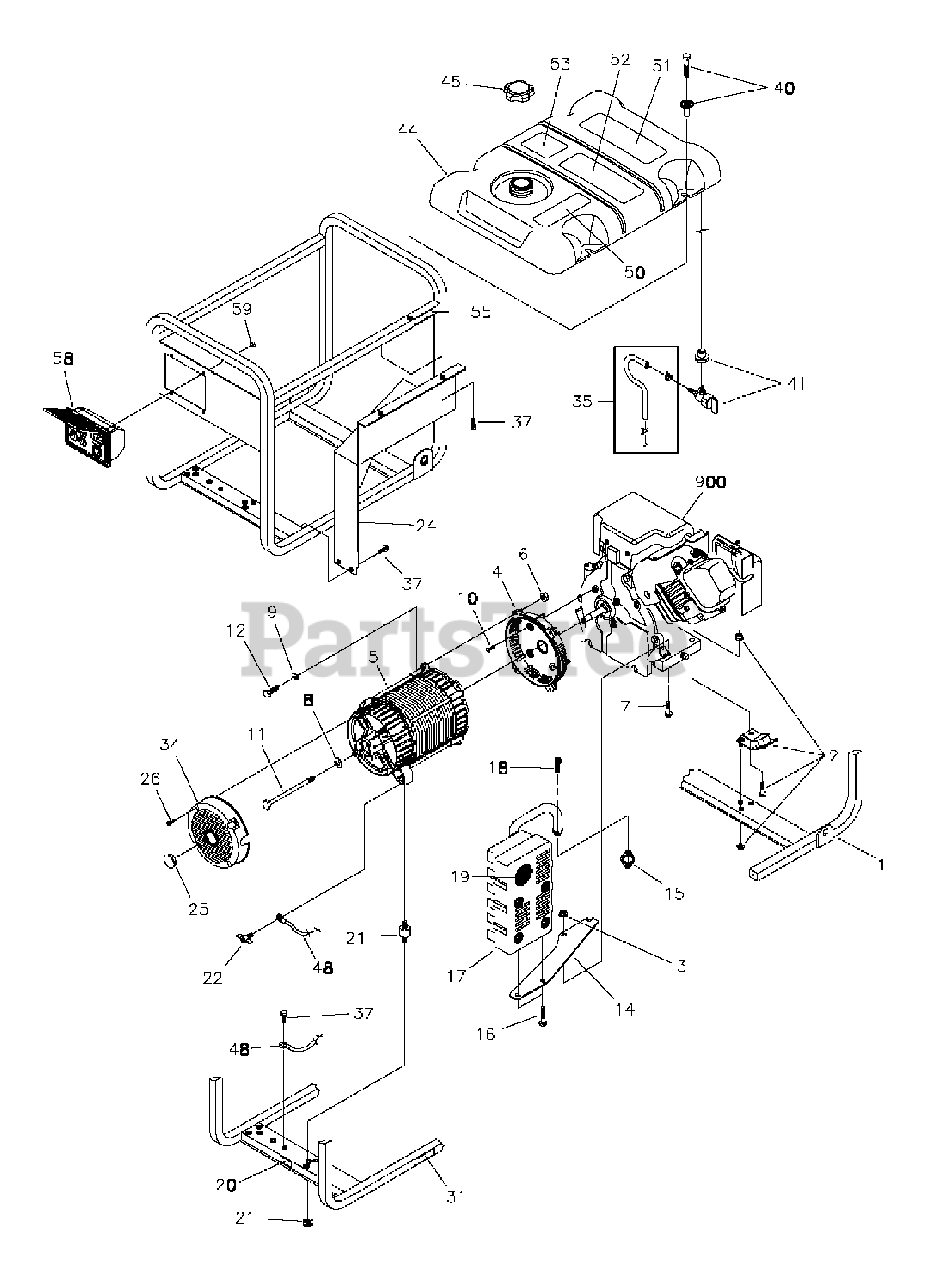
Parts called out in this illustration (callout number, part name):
1	CRADLE (Includes #'s 20, 31, & 55)
2	KIT, Vibration Mount, 45°
3	NUT, M8 Flange Serrated
4	HOUSING, Engine Adapter
5	ALTERNATOR ASSEMBLY
8	WASHER, Flat M8.4 x 22.2 x 3
9	* WASHER, 5/16 - M8 Lock
10	HHCS, 5/16-24 x 3/4, SEMS
11	HHCS, 5/16-24 x 7-7/8" Lg
14	BRACKET, Muffler
15	Gasket-Exhaust
19	SCREEN, Spark Arrest
20	DECAL, Ground, Green
21	KIT, Vibration, Mount
22	SCREW, Wing M6 - 1.0 x 16
24	SHIELD, Heat
26	SCREW, M5-0.8 x 10,Taptite
31	DECAL, Warning Exhaust
34	COVER, Bearing Carrier with Cap
35	KIT, Hose Formed
37	HHCS, 12 - 14 x 7/8" Self Driller
40	KIT, Fuel Tank Hardware (Includes Qty 4)
41	KIT, Valve, Fuel Tank
44	ASSY, Tank, Fuel (Includes # 41, 50, 51, 52 & 53)
45	CAP, Fuel
48	WIRE, Ground
50	DECAL, Instruction, Fuel Level
51	DECAL, Danger
52	DECAL, Operating Instructions
53	DECAL, Warning, CO
55	DECAL, Fuel Shut Off
58	ASSY, Control Panel
900	ENGINE, Briggs & Stratton, 6.5HP INTEK
